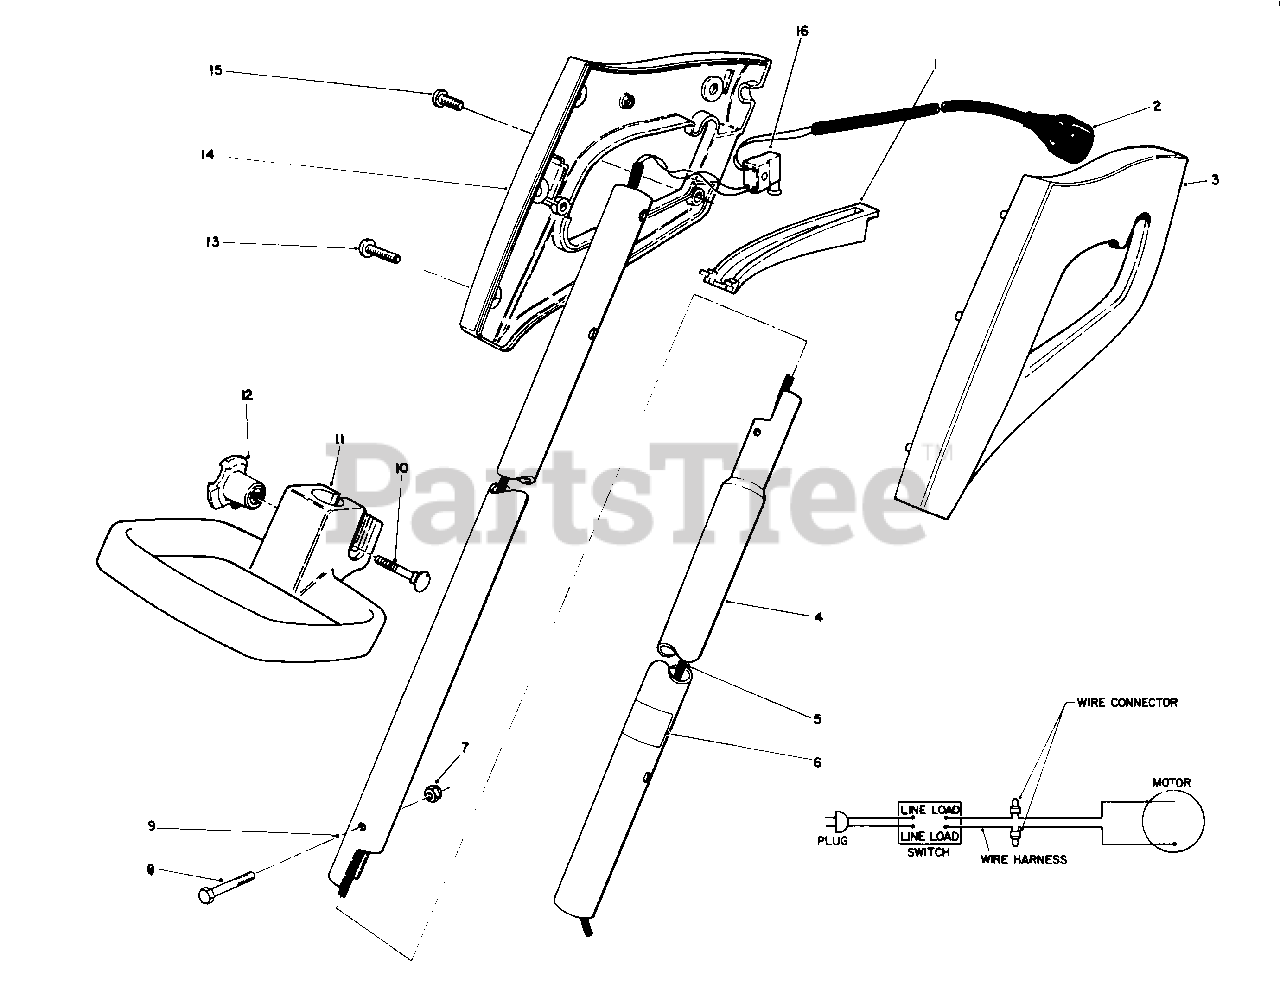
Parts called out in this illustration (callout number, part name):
1	Bar Switch
2	Plug-Pig Tail
3	Grip-L.H.
4	Tubing-Lower Extension
5	Wire Harness
6	Decal-Serial No. Replacement
8	Screw-Machine Hex Hd.
9	Tubing-Upper Extension
10	Carriage Bolt
11	Handle-Adjustable
12	Knob-Adjustable
13	Screw-Cross Recess Pan Head Thread Forming
14	Grip R.H.
15	Screw-Thread Forming
16	Switch-Single Speed
